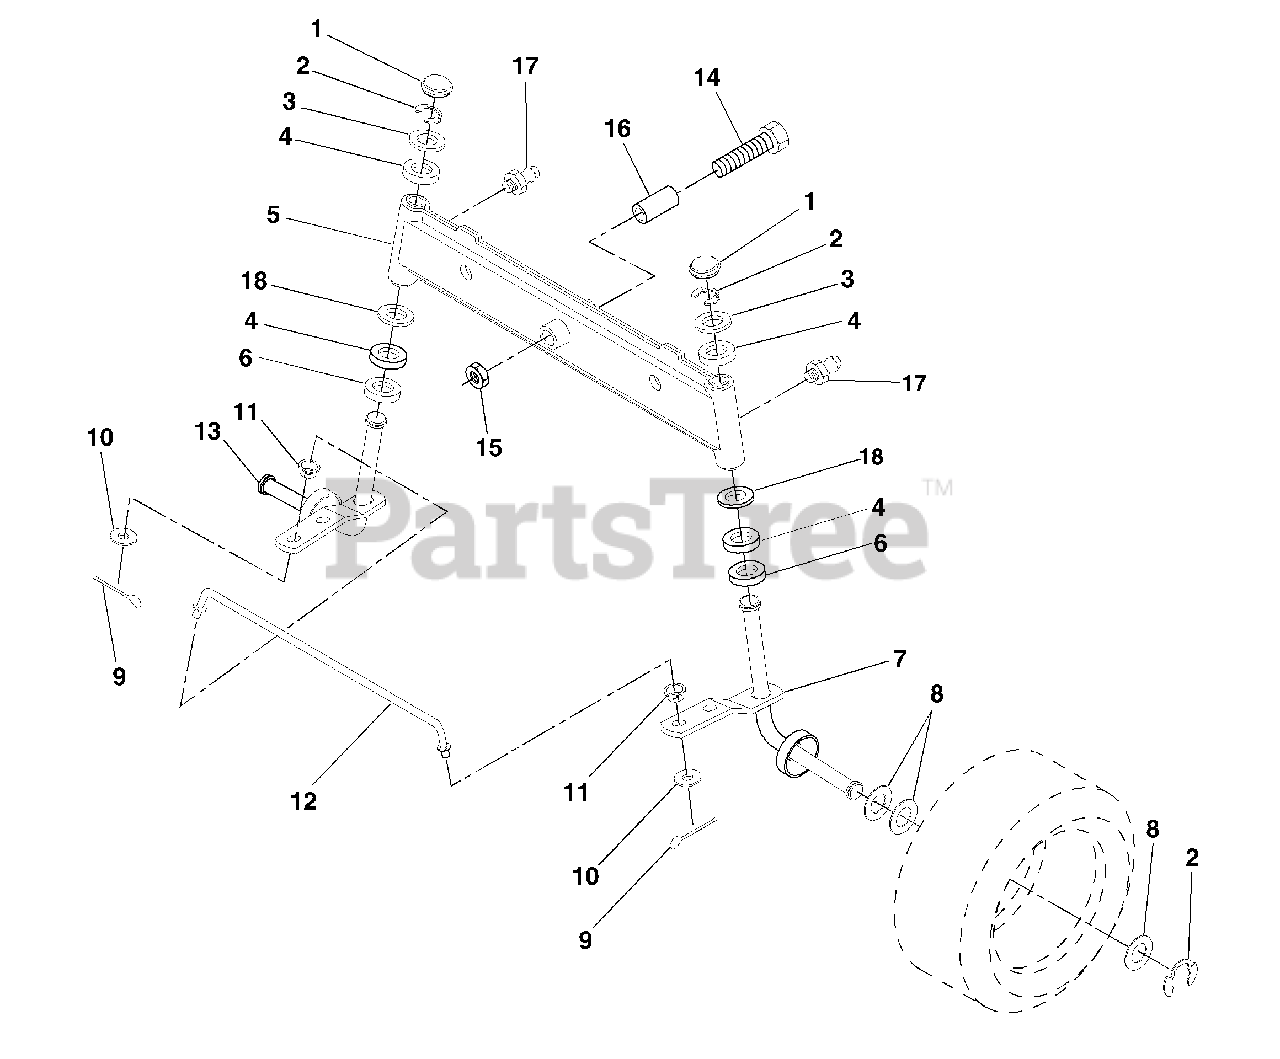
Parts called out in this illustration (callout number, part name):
1	Cap, Spindle
2	Ring, Clip
3	Washer 25/32 x 1-5/8 x 16 Ga.
4	Nyliner
5	Axle, Front
6	Bearing, Thrust
7	Spindle, R.H. Asm.
8	Washer 25/32 x 1-1/4 x 16 Ga.
9	Pin, Cotter 1/8 x 3/4
10	Washer 13/32 x 13/16 x 16 Ga.
12	Rod, Tie
13	Spindle, L.H. Asm.
14	Bolt Hex 5/1-11 x 3-1/2
15	Nut, Lock Flange 5/8-11
16	Spacer Bearing Axle
17	Fitting Grease
18	Washer 27/32 x 1-1/4 x 16 Ga.
